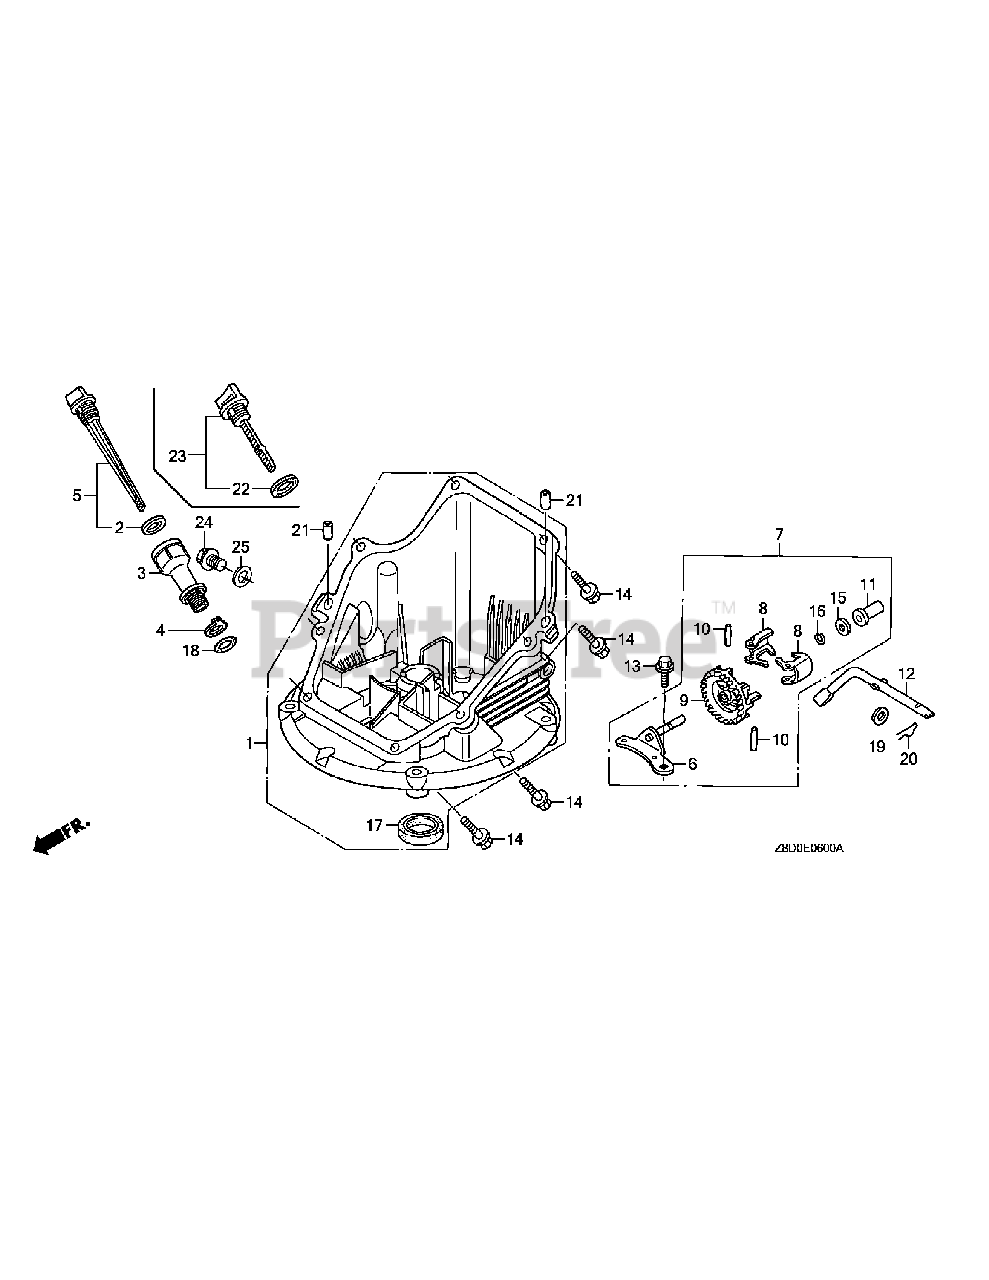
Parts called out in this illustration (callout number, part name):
1	Cylinder Barrel Assembly
2	Oil Filler Cap Packing
3	Oil Fill Extension
4	Extension Lock Washer
5	Oil Level Gauge Assembly
6	Governor Holder Shaft Comp.
7	Governor Assembly
8	Governor Weight
9	Governor Weight Holder
10	Governor Weight Pin
11	Governor Slider
12	Governor Arm Shaft
13	Flange Bolt, 6 x 14
14	Flange Bolt, 6 x 25
15	Thrust Washer, 6mm
16	Governor Holder Clip
17	Oil Seal, 28 x 41.25 x 6
18	O-Ring, 14.8 x 2.4
19	Plain Washer, 6mm
20	Lock Pin, 8mm
21	Dowel Pin, 8 x 20
22	Oil Filler Cap Packing
23	Oil Level Gauge Assembly
24	Drain Plug Bolt, 12 x 15
25	Drain Plug Washer, 12mm
